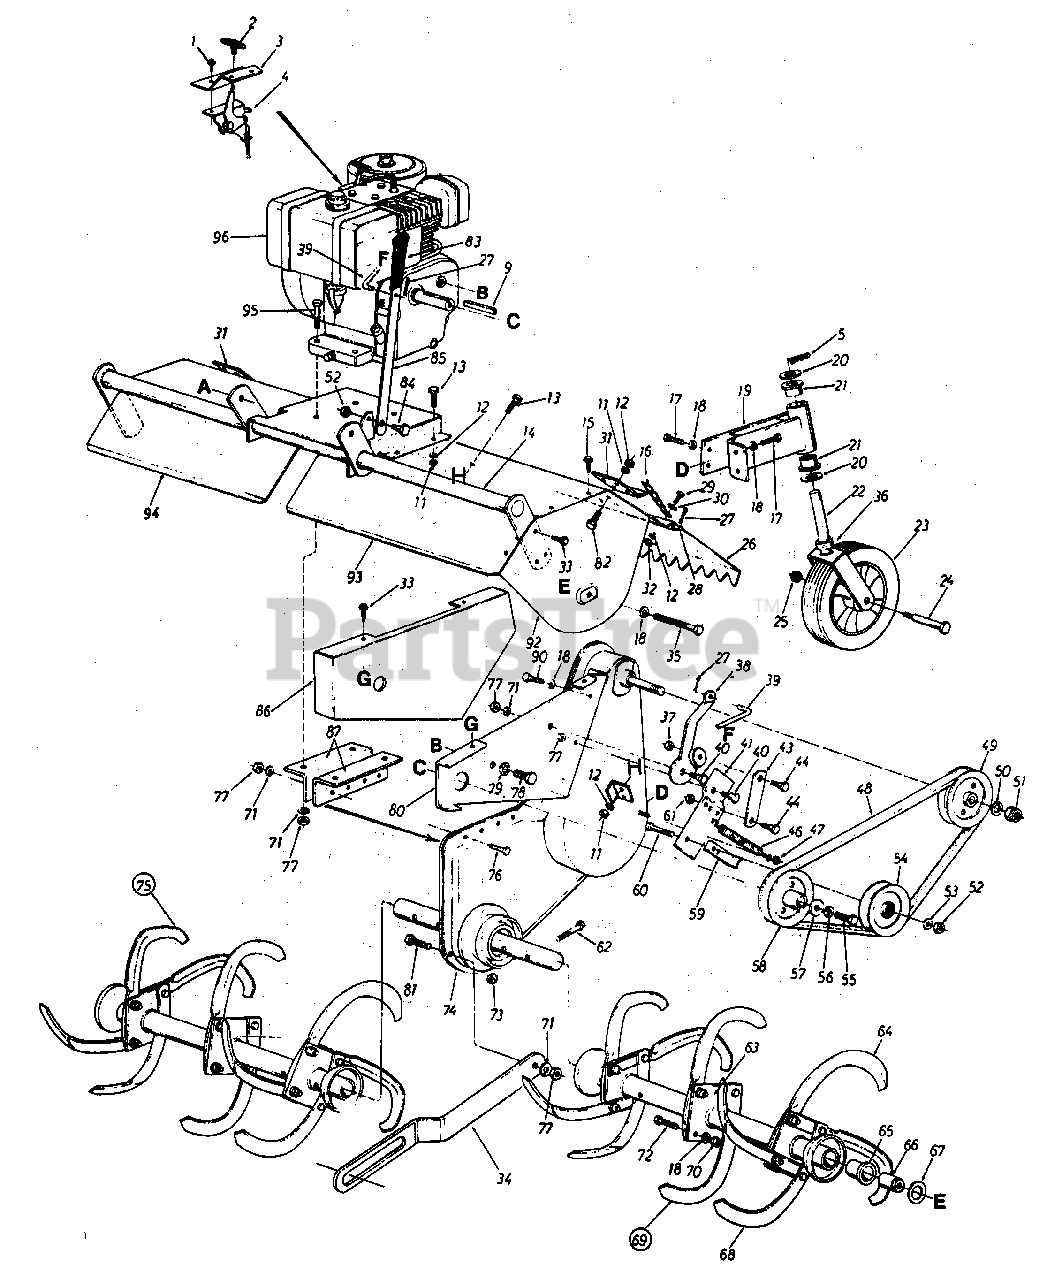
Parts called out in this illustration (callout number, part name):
1	Hex Wash. Hd. Self-Tap Scr. #8 x .50" Lq
2	Throttle Control Knob- (Service Only)
3	Throttle Control Bracket
4	Throttle Control Ass'y. Comp.
5	Internal Cotter Pin
11	Hex Nut 1/4-28 Thd.
12	L-Wash. 1/4" I.D.'
13	Hex Bolt 1/4-28 x .62" Lg.
16	#2 Dog Chain x 20" Lg. (2 Req'd.)
17	Hex Bolt 3/8-24 x .75" Lg.'
18	L-Wash. 3/8" I.D.
21	Flange Bearing 3/4" I.D. x 1.00" O.D.
22	Swivel Wheel Caster
23	Wheel Assembly 10.0 x 2.75
24	Shoulder Bolt .623" I.D. x 3.62" Lg.
25	Hex Cent. L-Nut 7/16-14 Thd.
28	L.H. Flap Rod
29	Hex Bolt 1/4-20 x .62" Lg.
30	Fl-Wash. 1/4" I.D.
33	Hex Wash. Hd. Self-Tap Scr. 1/4" x.62" Lg.
35	Hex Bolt 3/8-16 x 1.25" Lg.
36	Spacer .752" I.D. x 1.25" O.D.
37	Hex Cent. L-Nut 5/16-18 Thd.
40	Shoulder Bolt 7/16" Dia. x 1.75" Lg.
46	Extension Spring .62 O.D. x 6.12" Lg.
47	Hex Crown Nut 3/8-24 Thd.
48	"V"-Belt 1/2 " x 43 " Lg. (Kevlar)
49	1/2" "V"-Pulley 4.75" O.D. x .625" Bore
50	L-Wash. 5/8" I.D.
51	Hex Ins. L-Nut 5/8-18 Thd.
52	Hex Cent. L-Nut 3/8-16 Thd.
53	Fl-Wash. 3/8" I.D.
54	Idler Pulley 4.0" O.D.
56	L-Wash 7/16" I.D.
57	Fl-Wash. 7/16" I.D. x 1.38" O.D.
58	1/2" "V"-Pulley .475" O.D. x 1.00" Bore
61	Hex Cent. L-Nut 5/16-18 Thd.
62	Hex Bolt 7/16-14 x 2.00" Lg.
65	Flange Bearing 1.00" I.D.
67	Thrust Wash. 1/2" I.D. x 1.55" O.D.
69	Tine Assembly Comp.-L.H.
70	Hex Nut 3/8-24 Thd.
71	L-Wash. 5/16" I.D.
72	Hex Bolt 3/8-24 x 1.50" Lg.
73	Hex Cent. L-Nut 7/16-14 Thd.
77	Hex Nut 5/16-18 Thd.
78	Hex Bolt 1/2-20 x .88" Lg. (Grade 5)
79	L-Wash. 1/2" I.D.
80	Clutch Support Bracket
81	Purchase Locally
82	Hex Bolt 1/4-28 x .75" Lg.*
83	Plastic Grip
84	Shoulder Bolt .498 Dia. x .212 Lg.
85	Clutch Handle
90	Hex Bolt 3/8-16 x .62" Lg
96	8 H.P. Engine
